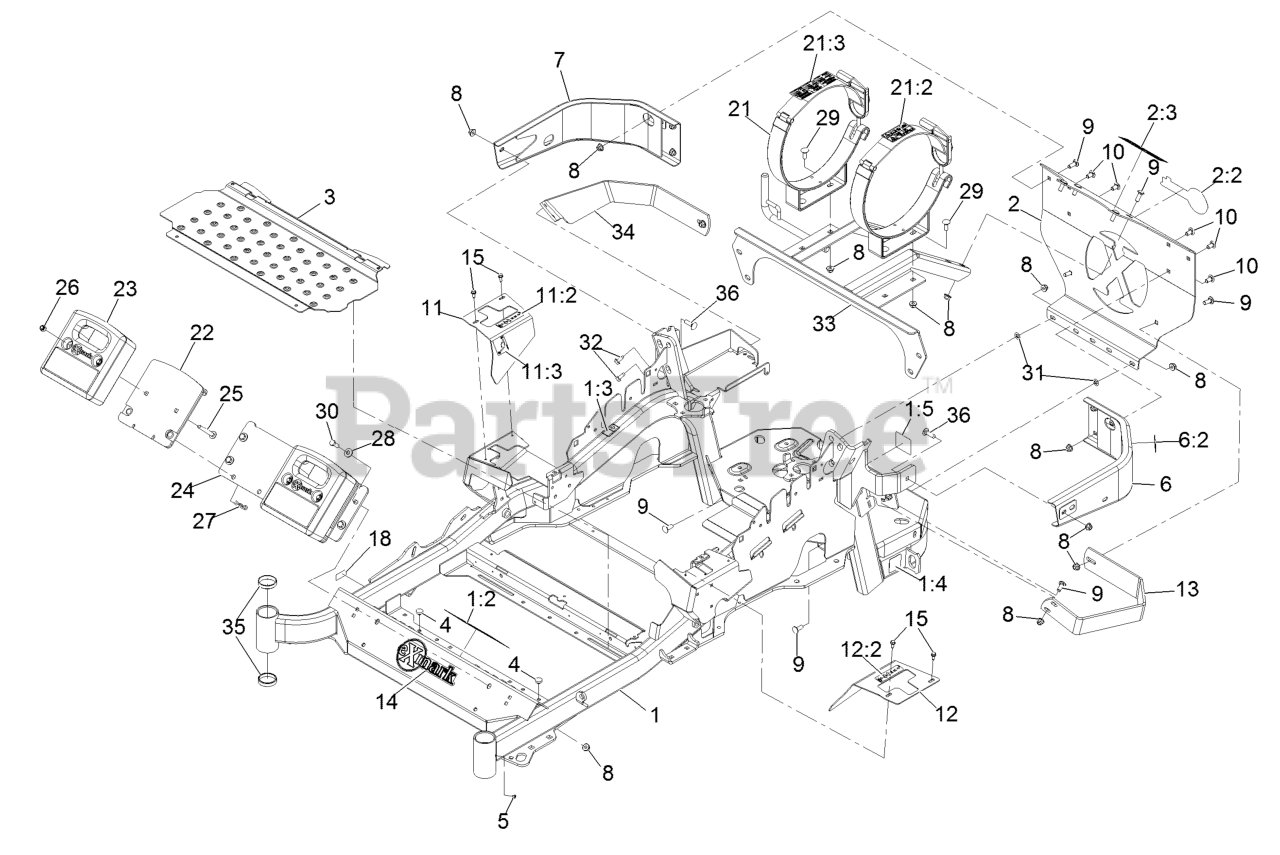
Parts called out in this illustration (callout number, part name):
1	MAINFRAME ASM
1:2	DECAL-DANGER
1:3	DECAL-WARNING
1:4	DECAL-HAZARD, PINCHED FINGER
1:5	DECAL-SPARK ARRESTER
2	REAR GUARD-LP W/DECALS
2:2	DECAL-EXMARK LOGO
2:3	Decal-LPG Fuel Tank Replacement
6	LH BUMPER ASM
6:2	DECAL-WARNING
7	BUMPER-RH
8	NUT-HF, NI
9	SCREW-CARR
10	SCREW-CARR
11	RH MOTION CONTROL COVER ASM
11:2	DECAL-CONTROL, MOTION
11:3	DECAL-PARK BRAKE, CE
12	LH MOTION CONTROL COVER ASM
12:2	DECAL-CONTROL, MOTION
13	GUARD-MUFFLER
14	DECAL-EXMARK LOGO
15	SCREW-HWH
18	Decal-Patent
21	TANK BRACKET ASM (SET)
21:2	Decal-LPG Warning
21:3	Decal-LPG Tank Spec
22	WLD,WEIGHT MOUNT
23	WEIGHT,CAST 36LB
24	PLATE,WEIGHT ASM MOUNT
25	SCREW-CARR
26	NUT-LOCK, NI
27	PIN-HAIR
28	WASHER-BELLEVILLE
29	BOLT-CARR
30	SCREW-HH
31	NUT-PUSH
32	Screw-HWH 5/16-18 X 3/4 Tf
33	SUPPORT-TANK
34	STRAP-GUARD
35	CUP-BEARING
36	BOLT-CARR
